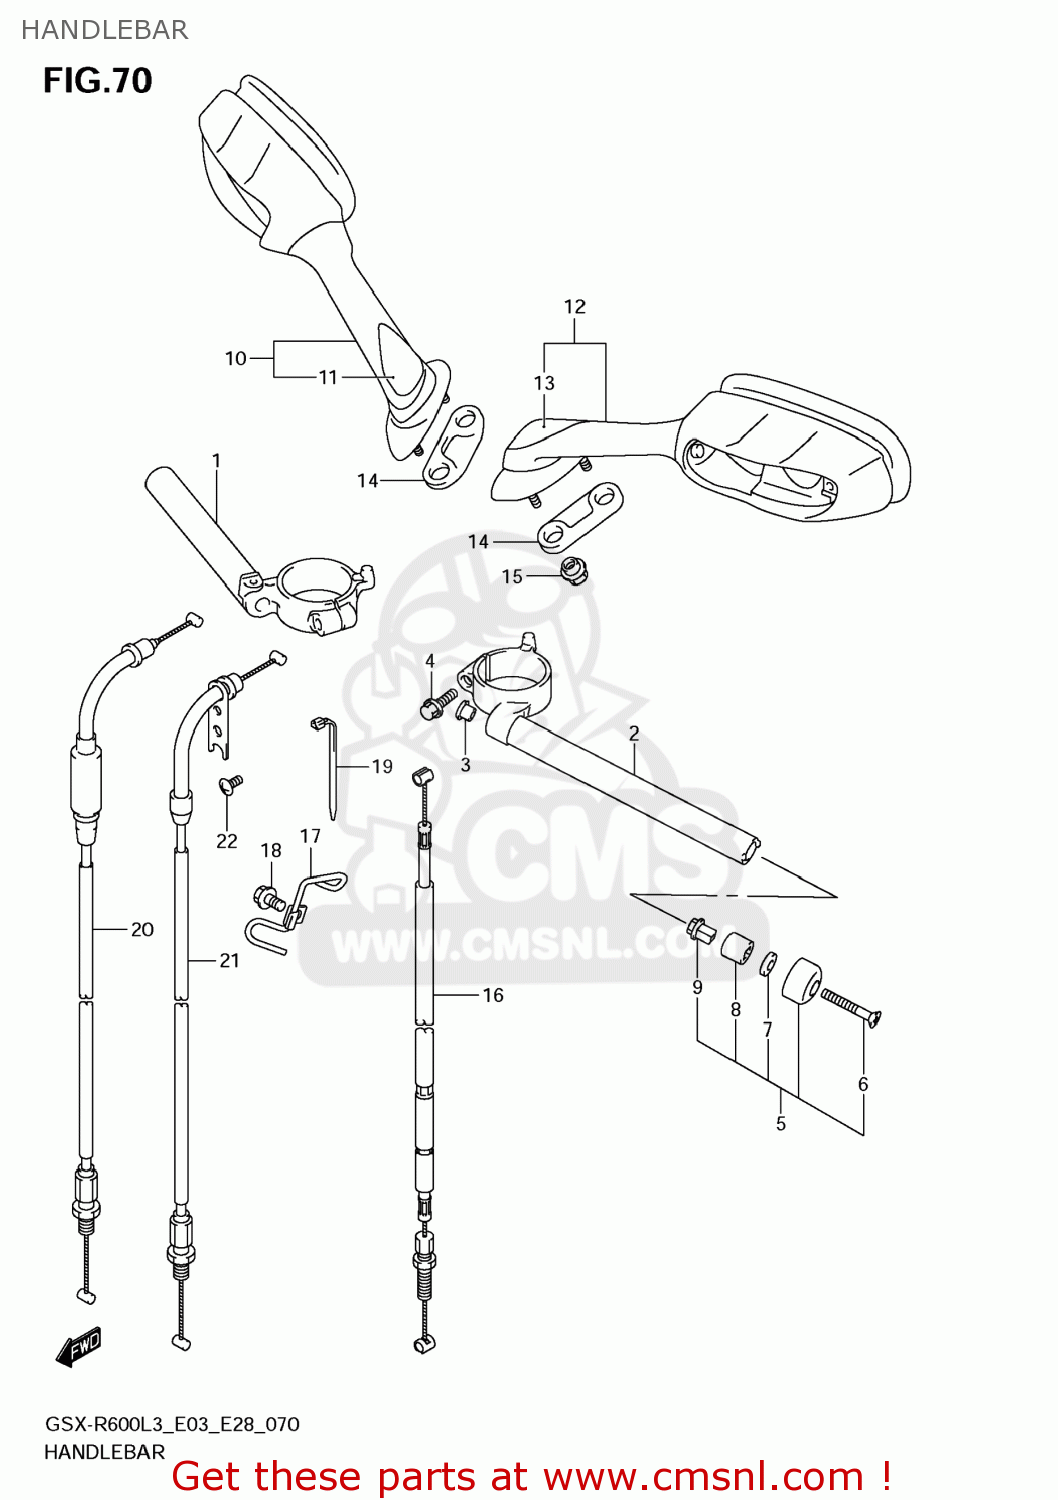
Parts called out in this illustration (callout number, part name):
1	HANDLEBAR,R
2	HANDLEBAR,L
3	CAP,HANDLEBAR
4	BOLT(8X32)
5	BALANCER SET,HANDLEBAR
6	SCREW
7	WASHER(6.5X16X4)
8	EXPANDER,HANDLE BALANCER
9	NUT,HANDLE BALANCER
10	MIRROR ASSY,RR VIEW,R
11	CAP,R
12	MIRROR ASSY,RR VIEW,L
13	CAP,L
14	CUSHION,RR VIEW MIRRROR,R
15	NUT,RR VIEW MIRROR
16	CABLE ASSY,CLUTCH
17	GUIDE,CABLE
18	BOLT
19	CLAMP(L:154)
20	CABLE ASSY,THROTTLE NO.1
21	CABLE ASSY,THROTTLE NO.2
22	SCREW(5X10)
